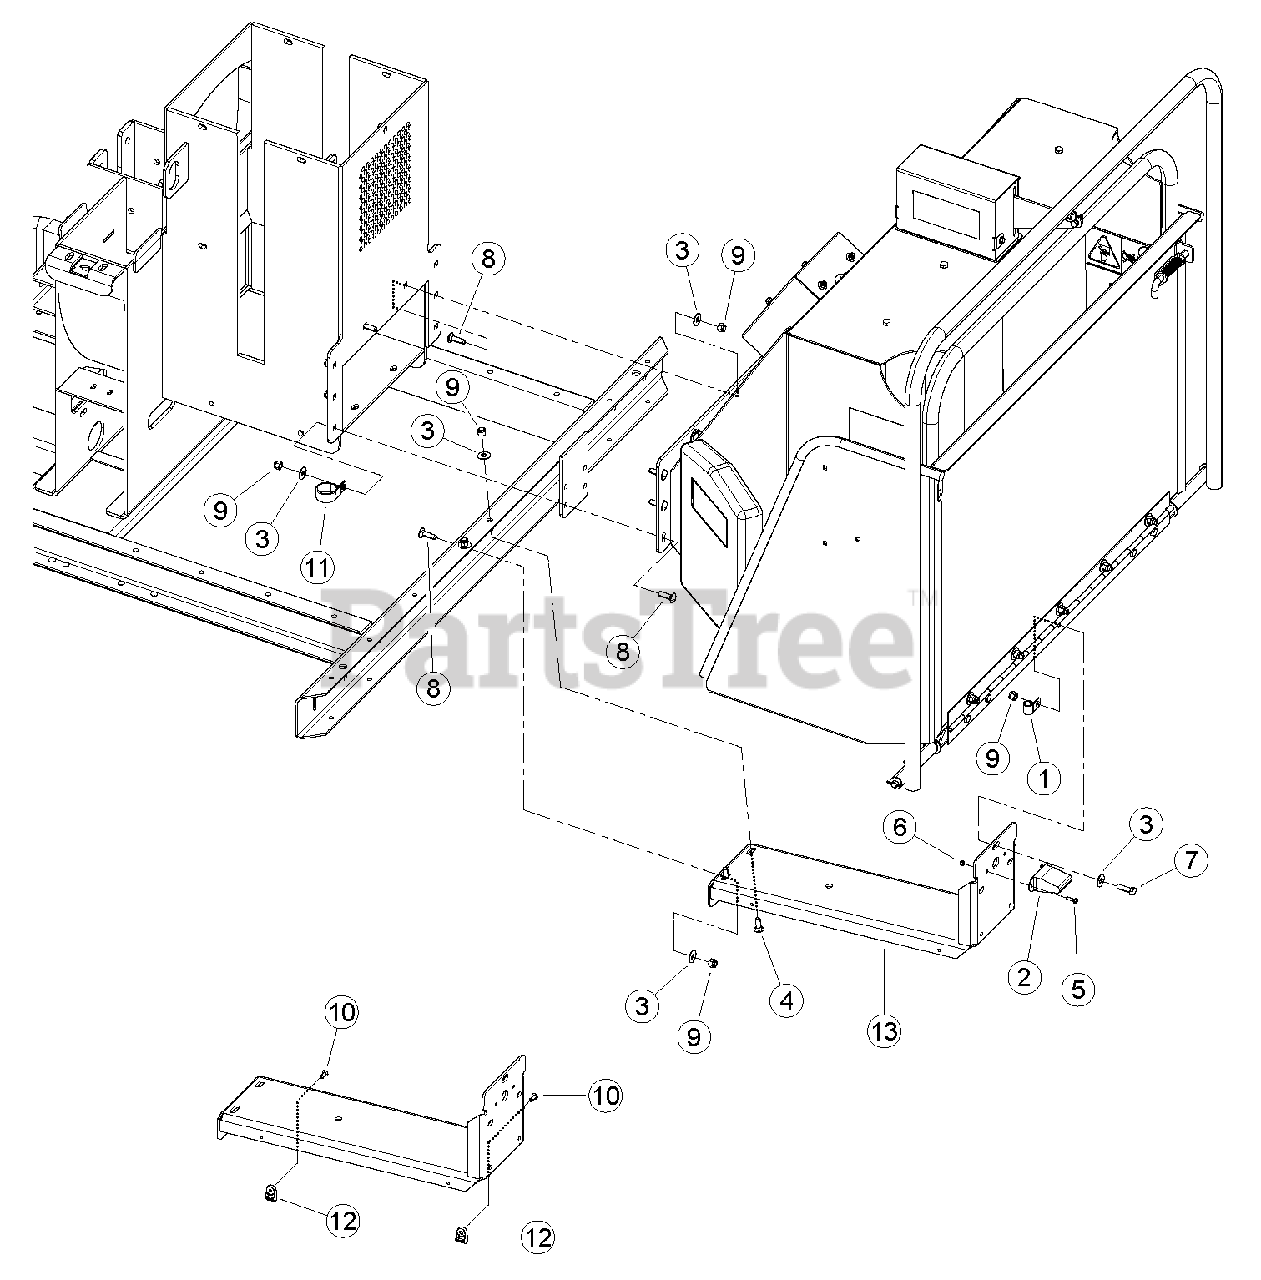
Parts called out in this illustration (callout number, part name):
1	CLAMP, 9/16" COATED
2	LIGHT, LICENSE PLATE
3	WASHER, 3/8 FLAT ZP
4	BOLT, 3/8 X 1 CRG GR5 NC ZP
5	SCREW, #10 X 3/4 HEX TAP SC
6	NUT, 8-32 NYLOCK
7	BOLT, 3/8 X 1-1/4 HEX HD GR5 ZP
8	BOLT, 3/8 X 1-1/4 CRG GR5 NC ZP
9	NUT, 3/8 NE NYLOCK ZP
10	RIVET, AL BLIND 1/4 X 3/4 DOME HEAD
11	CLAMP, 1-9/16" COATED METAL
12	CLAMP, CABLE MOUNT
13	SUPPORT, CHUTE/SPARE
